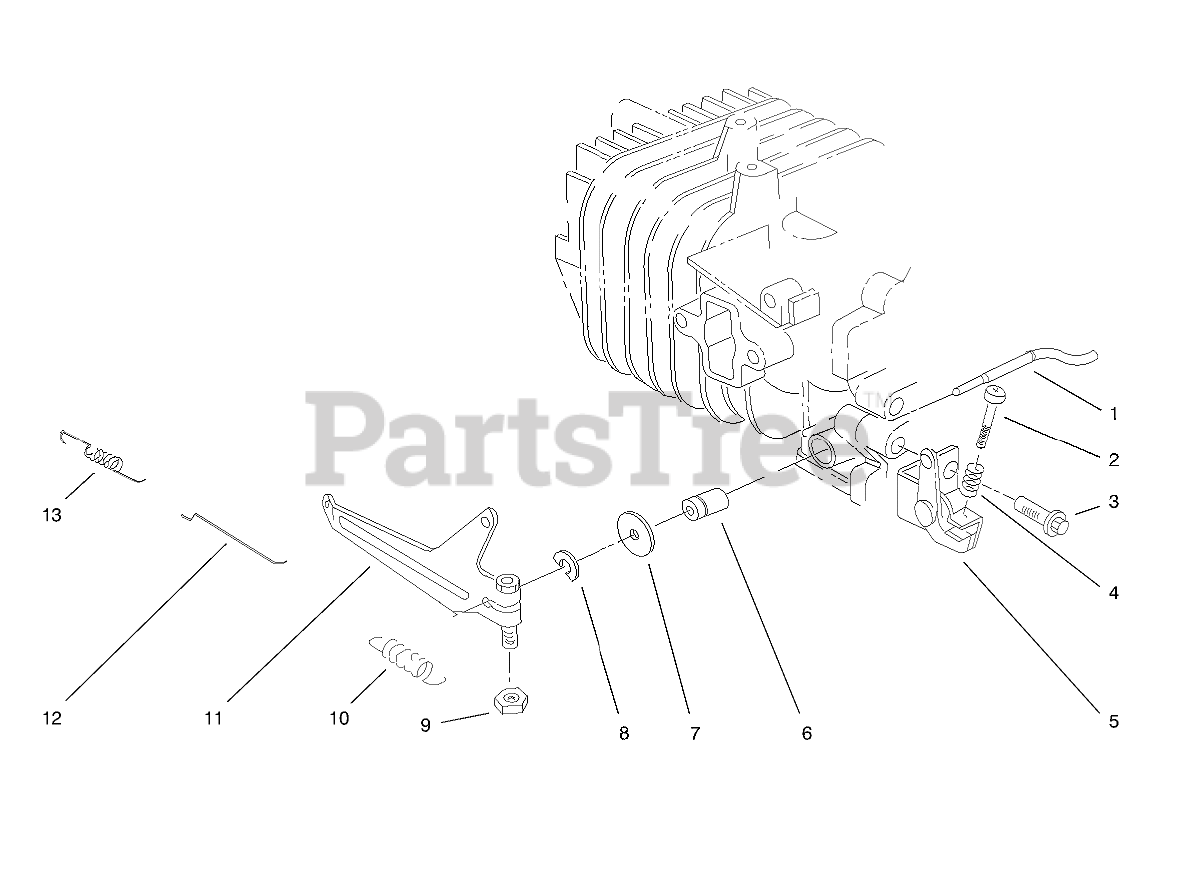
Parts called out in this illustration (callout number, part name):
1	SHAFT
2	SCREW
4	SPRING
5	GOV SPR BRKT
6	SEAL-OIL
7	WASHER
8	E-RING
10	GOV SPRING
11	GOV ARM
12	CARB ROD
13	CARB SPRING
